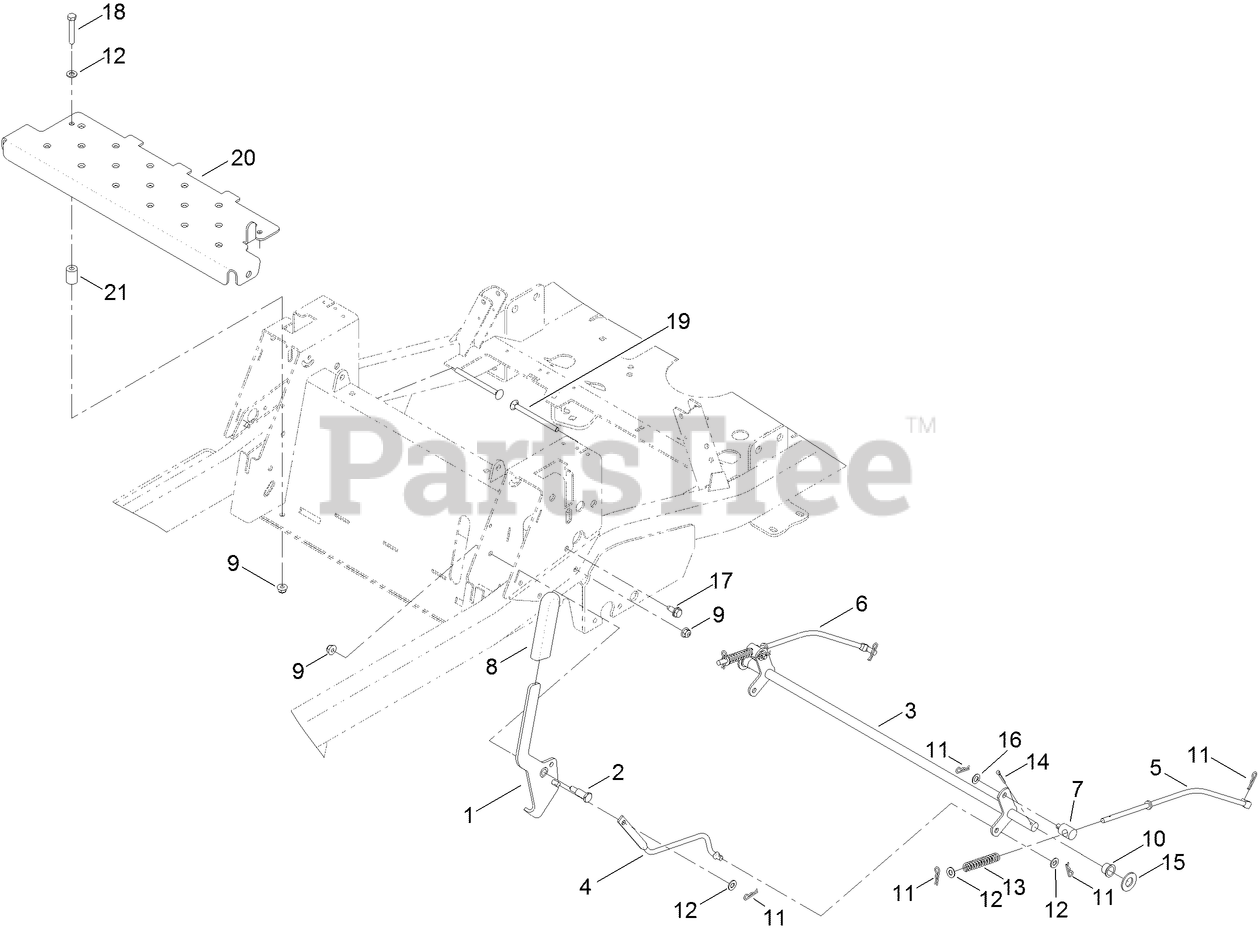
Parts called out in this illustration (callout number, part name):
1	BRAKE HANDLE ASM
2	SCREW-SHOULDER
3	BRAKE BELLCRANK ASM
4	LINK-BRAKE
5	ROD-BRAKE, LH
6	ROD-BRAKE, RH
7	FITTING-ROD
8	GRIP-LEVER
9	NUT-HF, NI
10	BUSHING-FLANGE, NI
11	PIN-COTTER
12	WASHER-PLAIN
13	SPRING-RETURN, NEUTRAL
14	PIN-COTTER
15	WASHER-FLAT
16	WASHER
17	SCREW-HWHTF
18	SCREW-HH
19	SCREW-CARR
20	PLATE-SUPPORT, FLOOR PAN
21	SPACER
